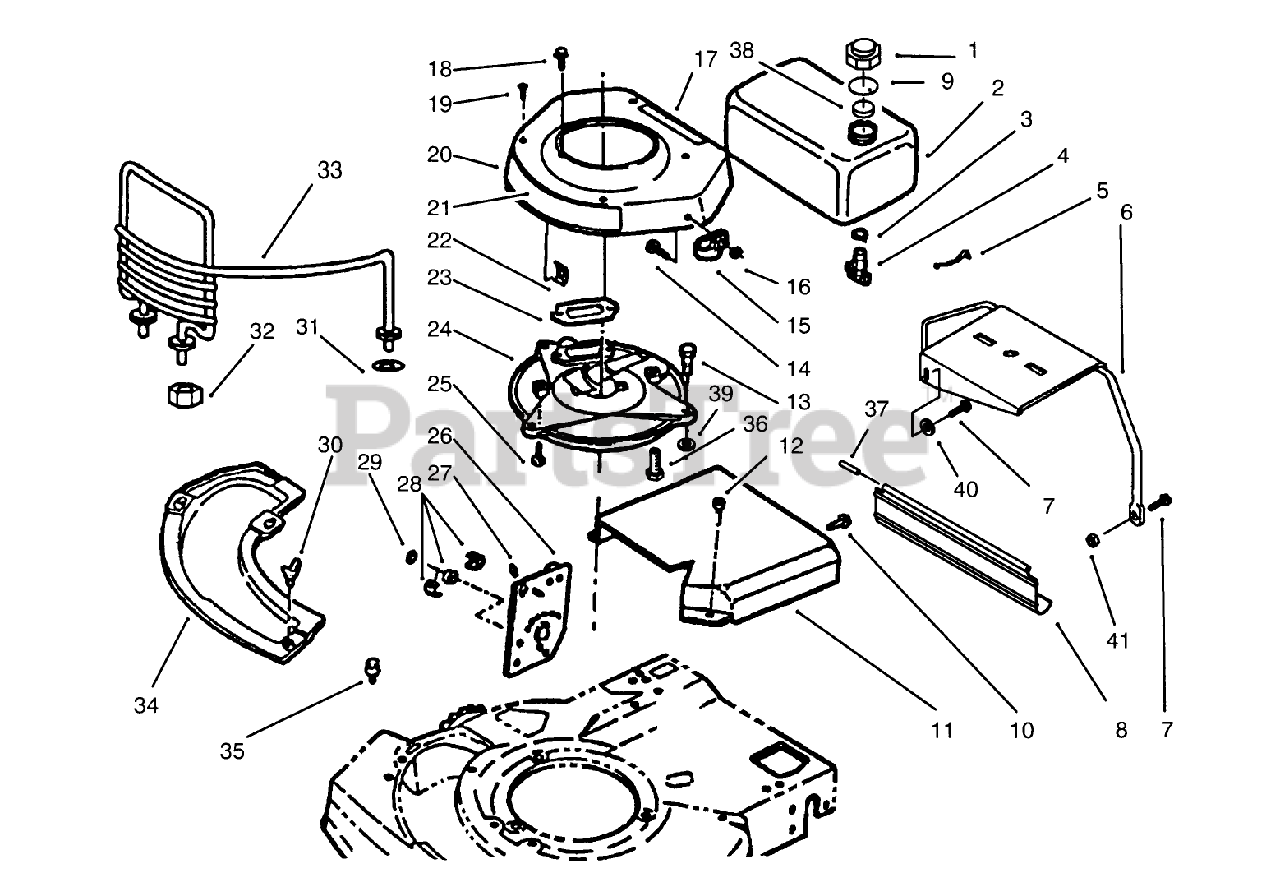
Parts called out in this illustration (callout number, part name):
2	TANK - FUEL
3	CLAMP - HOSE S
4	VALVE&SCREEN SM
6	BRACKET AY-TANK *B
8	SHIELD - TRAILING
9	GASKET S
12	SCREW SEMS TRM HEX HD
14	SCREW-HWH
16	NUT-LOCK, NI
18	SCREW SEMS SM
19	SCREW - SELF TAPPING
22	PUSHNUT F
23	GASKET-EXH. VF
24	MUFFLER PLATE F
25	SCREW V
26	HEIGHT ADJ AY-RH
27	**FITTING LINCOLN
28	REAR AXLE BEARING
32	NUT-LOCK, NI
35	SCREW-SEMS
36	SCREW-SEMS F
38	BAFFLE - FOAM SM
39	WASHER-FLAT
41	NUT-LOCK, NI
